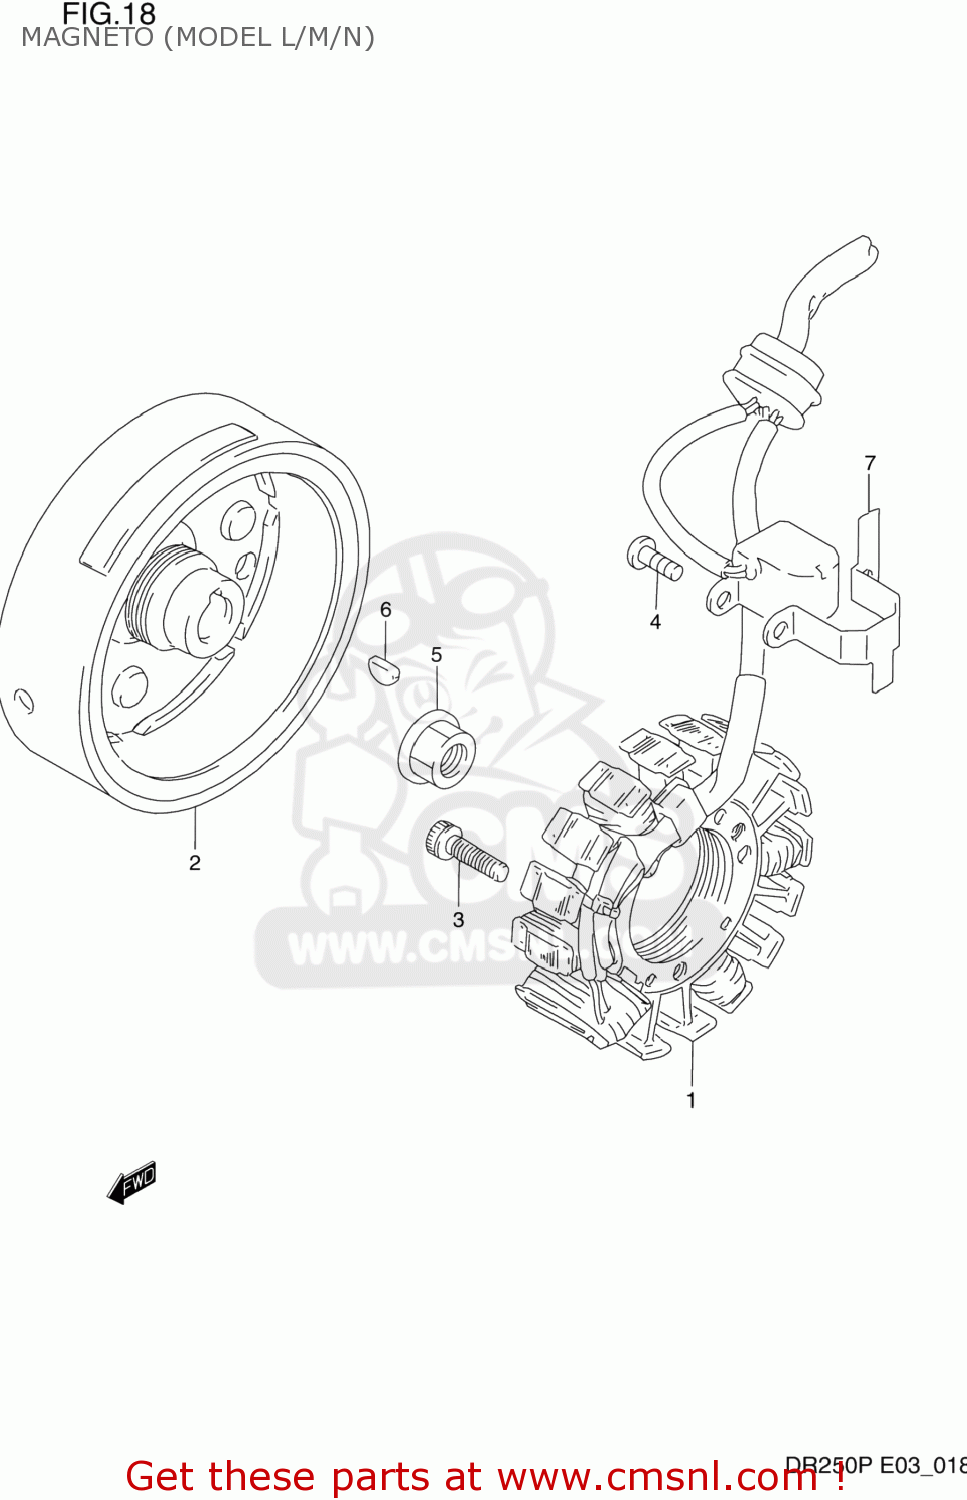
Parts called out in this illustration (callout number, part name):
1	STARTER ASSY
2	ROTOR
3	BOLT
4	SCREW
5	NUT
6	KEY 4MM
7	CLAMP,MAGNETO LEAD WIRE
